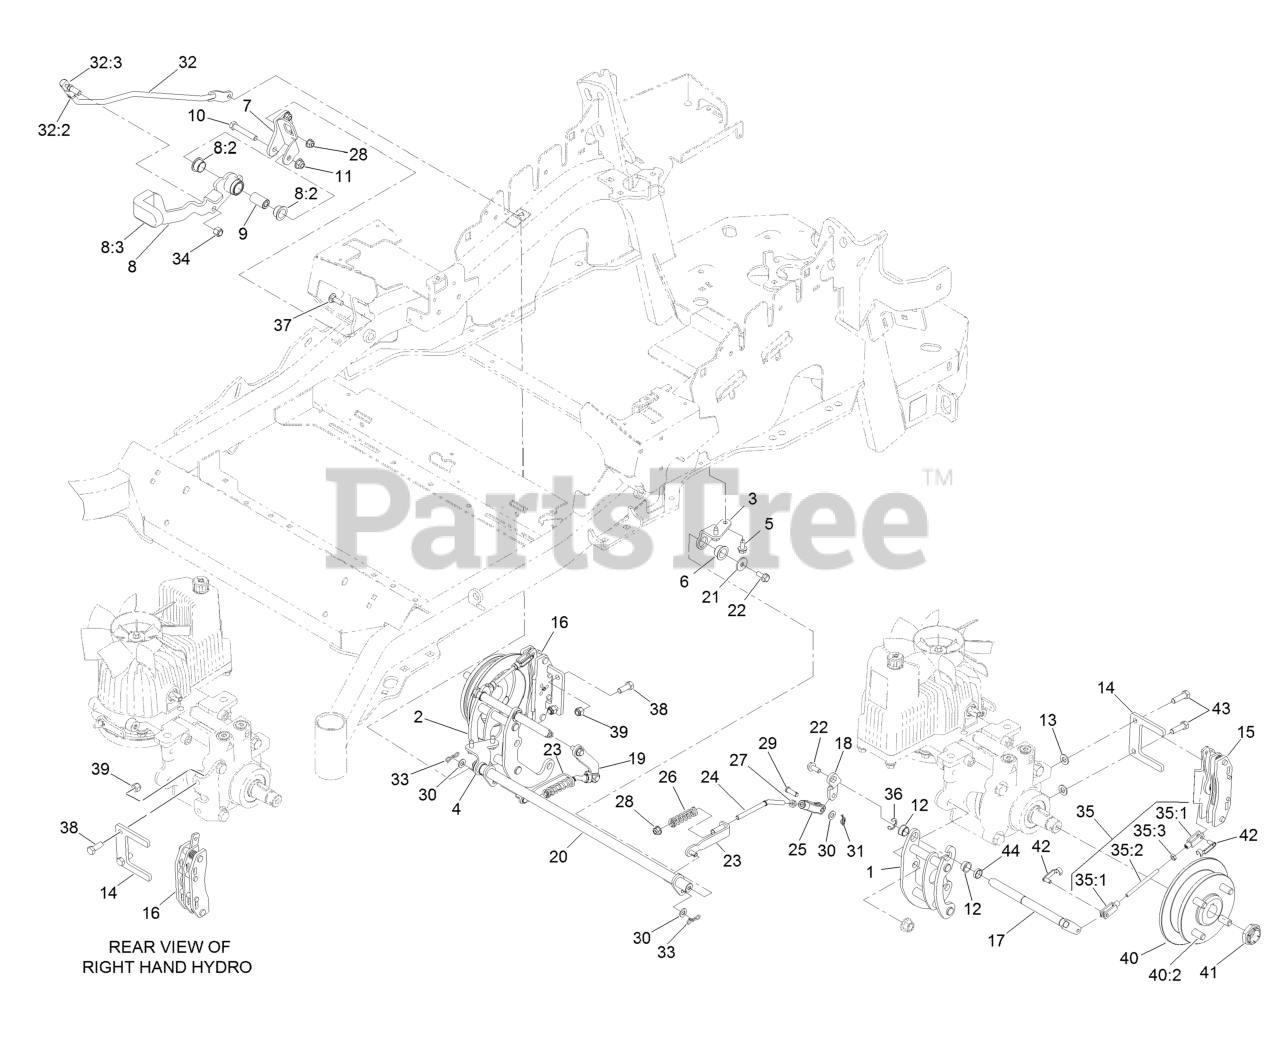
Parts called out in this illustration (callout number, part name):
1	Mount-Bellcrank, LH
2	Mount-Bellcrank, RH
3	Mount-Pivot, LH
4	Mount-Pivot, RH
5	Screw-HWHTF
6	Bushing-Flange
7	Bracket-Mount
8	Brake Lever ASM W/Grip
8:2	Bushing-Flange
8:3	Grip-Lever
9	Handle-Pivot, Brake
10	Screw-HH
11	Nut-HF, NI
12	Bushing
13	Washer-Flat
14	Plate-Mount, Brake
15	Caliper-Brake
16	Caliper-Brake, RH
17	Bellcrank
18	Arm-Inner, LH
19	Arm-Inner, RH
20	Shaft-Cross
21	Washer-Flat
23	Bracket-L
24	Linkage-Mid
25	Yoke-Offset
26	Spring-Compression
27	Nut-Jam
28	Nut-HF, NI
29	Pin-Clevis
30	Washer-Plain
31	Pin-Cotter, Locking
32	Front Linkage ASM
32:2	End-Tie Rod, RH
32:3	Nut-HJ
33	Pin-Cotter, Locking
34	Nut-Lock
35	Rear Linkage ASM
35:1	Yoke
35:2	Linkage, Rear
35:3	Nut-Jam
37	Bolt-CARR
38	Screw-HH
39	Nut-Lock, NI
40	Wheel Hub ASM
40:2	Stud-Wheel
41	Locknut
42	Pin-Clevis, Spring
43	Screw-Lock, Patch
